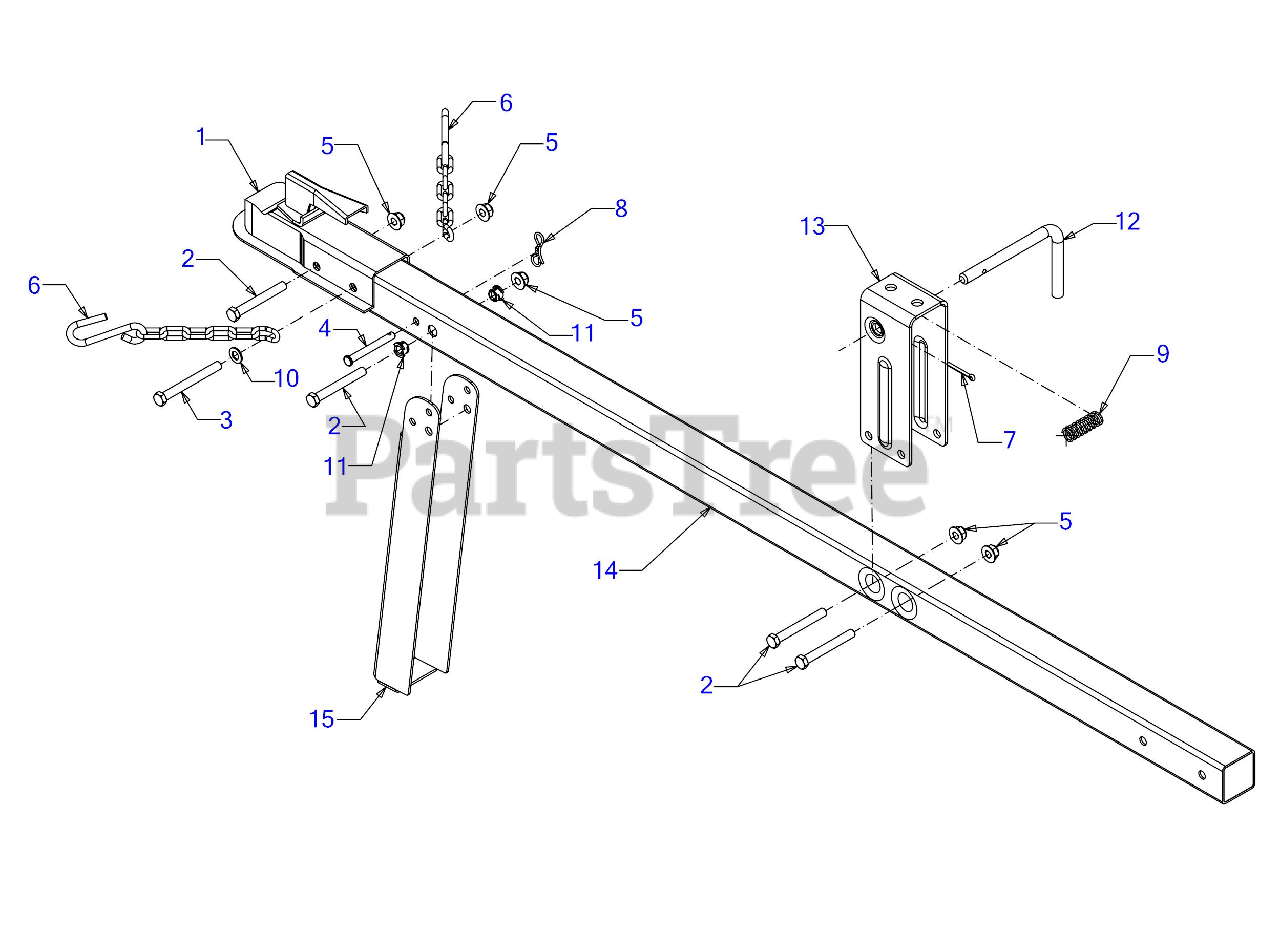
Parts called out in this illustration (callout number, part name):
1	HITCH COUPLING ASSEMBLY
2	SCREW 3/8-16 x 3 GR8
3	SCREW 3/8-16 x 3.50 GR5
4	CLEVIS PIN 5/16 x 2.5
6	LOGSPLITTER TOW CHAIN
7	COTTER PIN-5/32 DIA
8	PIN:COTTER
9	COMPRESSION SPRING
10	FLAT WASHER
11	BUSHING .380 ID
12	LATCH ROD
